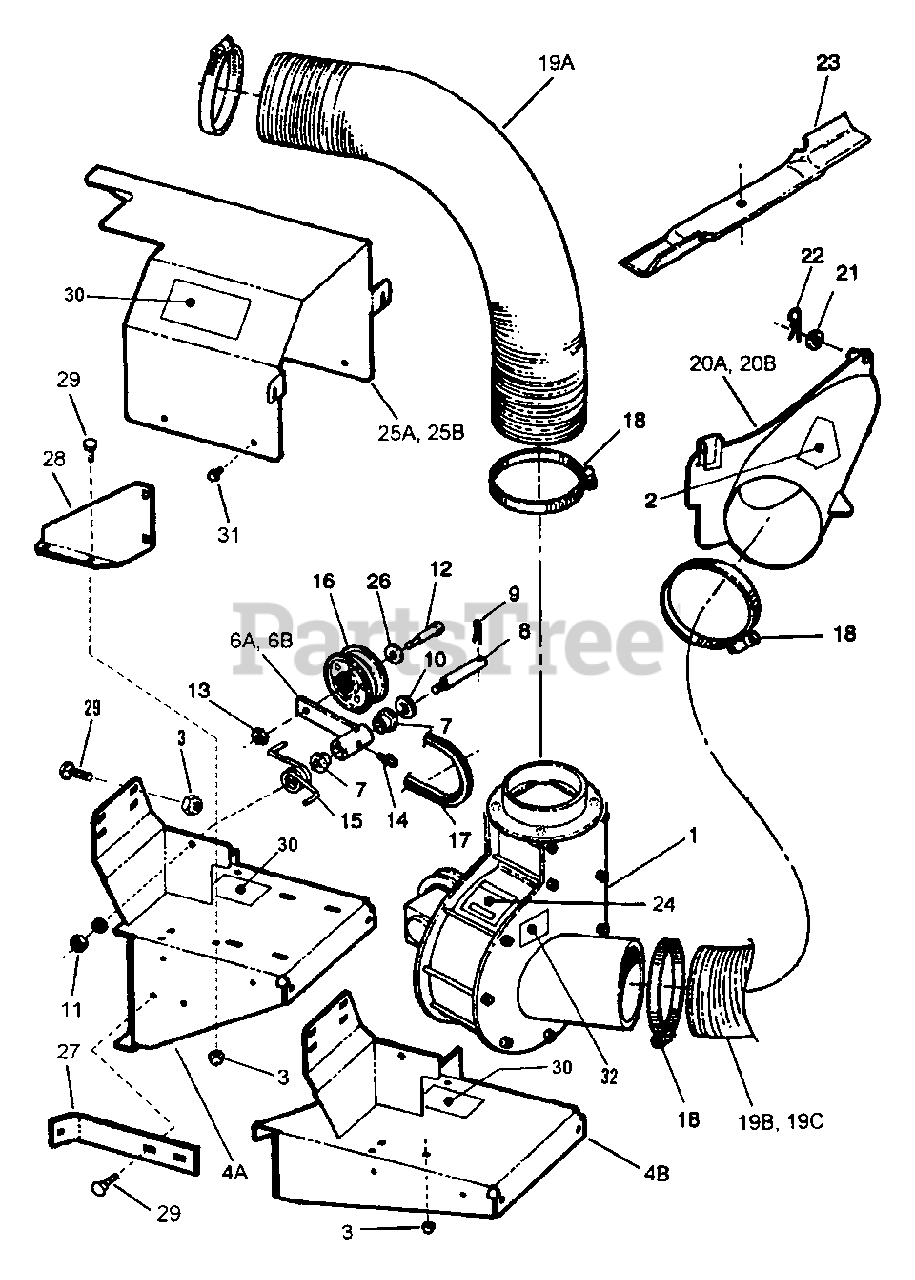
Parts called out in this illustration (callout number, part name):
1	ASSEMBLY, Blower
2	DECAL, Warning
3	NUT, 5/16-18 HEX NYLON LOCK
4A	ASSEMBLY, Blower Base
4B	ASSEMBLY, Blower Base (Kubota OFZ Models Only)
6A	WELDMENT, Idler Arm (5-3/8" overall length)
6B	WELDMENT, Idler Arm (7-3/8" overall length) (Kubota OFZ Models Only)
7	BEARING, 9/16" Flange
8	STUD, Idler
9	PIN, 1/8 x 3/4" Cotter
10	WASHER, 9/16 Narrow-Type Flat
11	NUT, 3/8-24 Hex Nyloc
12	SCREW, 3/8-16 x 1-3/4" Hex Head Cap, Grade 5
13	NUT, 3/8-16 HEX NYLON LOCK
14	FITTING, 3/16 Lube
15	SPRING, Torsion
16	Pulley, Idler
17	V-BELT (Kohler Mid Mount & OFZ Models Only)
18	CLAMP, 6" Hose
19A	HOSE, 6" I.D. x 42" Long, Flex.
19B	HOSE, 6" I.D. x 54" Long, Flex.
19C	HOSE, 6" I.D. x 66" Long, Flex. (Kubota OFZ Models Only)
20A	ASSEMBLY, 61" Catcher Adapter (shown)
20B	ASSEMBLY, 52" Catcher Adapter
21	WASHER, 1/2 Flat
22	PIN, 1/8 x 1/2" Hair
23	BLADE, 21" (61" Deck Only)
24	DECAL, Hand Danger
25A	GUARD, Belt
25B	GUARD, Belt (shown) (Kubota OFZ Models Only)
26	WASHER, 3/8" Flat
27	BRACE, Blower Mount (Kohler OFZ Only)
28	BRACE, Blower
29	BOLT, 5/16-18 x 3/4" Short Neck Carriage, Grade 5
30	DECAL, Danger
31	SCREW, 5/16-18 x 3/4" Hex Washer Self-Tapping
32	DECAL, Caution
